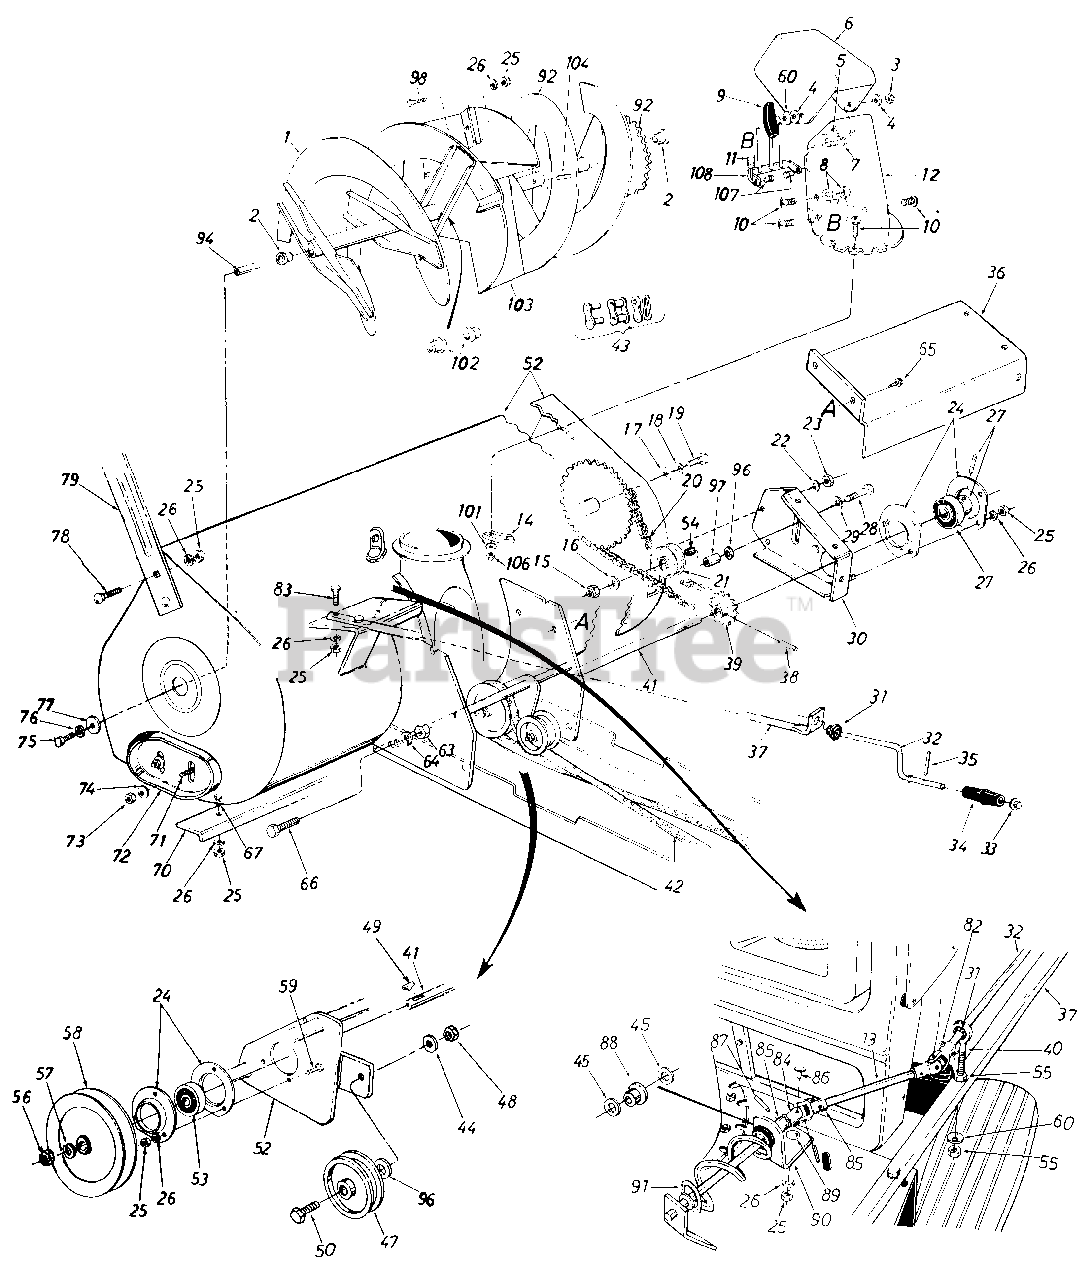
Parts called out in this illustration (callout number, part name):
3	Hex Cent. L.Nut 5/16-18 Thd.
4	Fl.Wash. .344" I.D.
5	Truss Mach. Scr. 5/16-18 x .75" Lg.
6	Upper Chute
7	Carriage Bolt 5/16-18 x 1.0" Lg.*
8	Hex L-Nut 1/4-20 Thd.
9	Hand Knob
10	Truss Mach Scr. 1/ 4 20 x .75" Lg.
11	Ext. Sprlng
12	Lower Chute
13	Chute Crank Extension Rod
14	Chute Flange Keeper
15	L.Nut 3/8-16 Thd.
16	Fl.Wash.
17	Fl.Wash.
18	Belleville Wash.
19	Hex Bolt 1/2-13 x 1.00" Lg.*
20	#420 Chain 1/2" Pitch x 77 Links
21	Plastic Idler 2.00" O.D.
22	L.Wash. 1/4" I.D.*
23	Hex Nut 1/4-20 Thd.*
24	Bearing Housing
25	Hex Nut 5/16-18 Thd.*
26	L.Wash. 5/l 6" I.D.*
27	Self-Aligning Bearing
28	Hex Bolt 3/8-16 x 1.75" Lg.*
29	Belleville Wash. 3/8" I.D.
30	Chain Guard Ass'y.
31	Nylon Bushing
32	Chute Crank .375 Dia. x 34.5" Lg.
33	Push Nut 3/8" Rod
34	Knob (Black)
35	Roll Pin
36	Drive Shaft Cover
39	14 Teeth Sprocket Ass'y.
40	Eyebolt 5/16-18 x 3.0" Lg.
41	Drive Shaft
42	"V" Belt
43	Master Link for #420 Chain
44	L.Wash. 3/8" I.D.*
45	Fl.Wash. .385 I.D. x .62" O.D.
47	Fl.ldler with Flanges
48	Hex Jam L.Nut 3/8-16 Thd.
49	#61 Hi-Pro Key 3/16 x 518" Dia.
50	Hex Bolt 3/8-16 x 1.75" Lg.*
52	Spiral Housing Ass'y.
53	Self-Aligning Bearing
54	Sleeve Bearing .50" I.D.
55	Hex Nut 5/16-18 Thd.*
56	Hex Nut 3/4-10 Thd.
57	L.Wash. 3/4" I.D.
58	"V"Pulley 750" I.D. x 6.00" O.D.
59	Hex Sems Bolt 5/16-18 x .75" Lg.
60	Bell Wash. .345" 1 D. x .88" O.D.
63	Hex Nut 1/2-13 Trd.
64	L.Wash. 1/2" I.D.'
66	Hex Bolt 1/2-13 x 2.75" Lg.*
67	Carriage Bolt 5/l6-18 x .75"*
72	Skid Shoe
73	Hex Jam Nut 3/8-16 Thd.
74	Belleville Wash. 3/8" I.D.
75	Hex Bolt 1/2-13 x 1.00" Lg.*
76	Belleville Wash. 1/2" I.D.
77	Fl.Wash.
78	Carriage Bolt 5/16-18 x .62" Lg.*
79	Grift Cutter
82	Coter Pin
83	Hex Bolt 5/16-18 x 1.50" Lg.*
84	Joint Block
85	Joint Bracket Ass'y.
86	Oval Head Rivet
87	Spring Pin Roll 1/8" Dia. x .75" Lg.*
88	Nylon Bushing
89	Carriage Bolt 5/16-18 x .75" Lg.
90	Chute Crank Bracket
91	Chute Crank Ass'y.
96	Flat Washel
97	Idler Spacer
98	Carriage Bolt 5/16-18 x .75" Lg.
101	Fl. Wash. 1/4" I.D.
102	Plastic Bushing
106	Hex L.Nut 1/4-20 Thd.
107	Shld. Nut 1/4-20 Thd.
